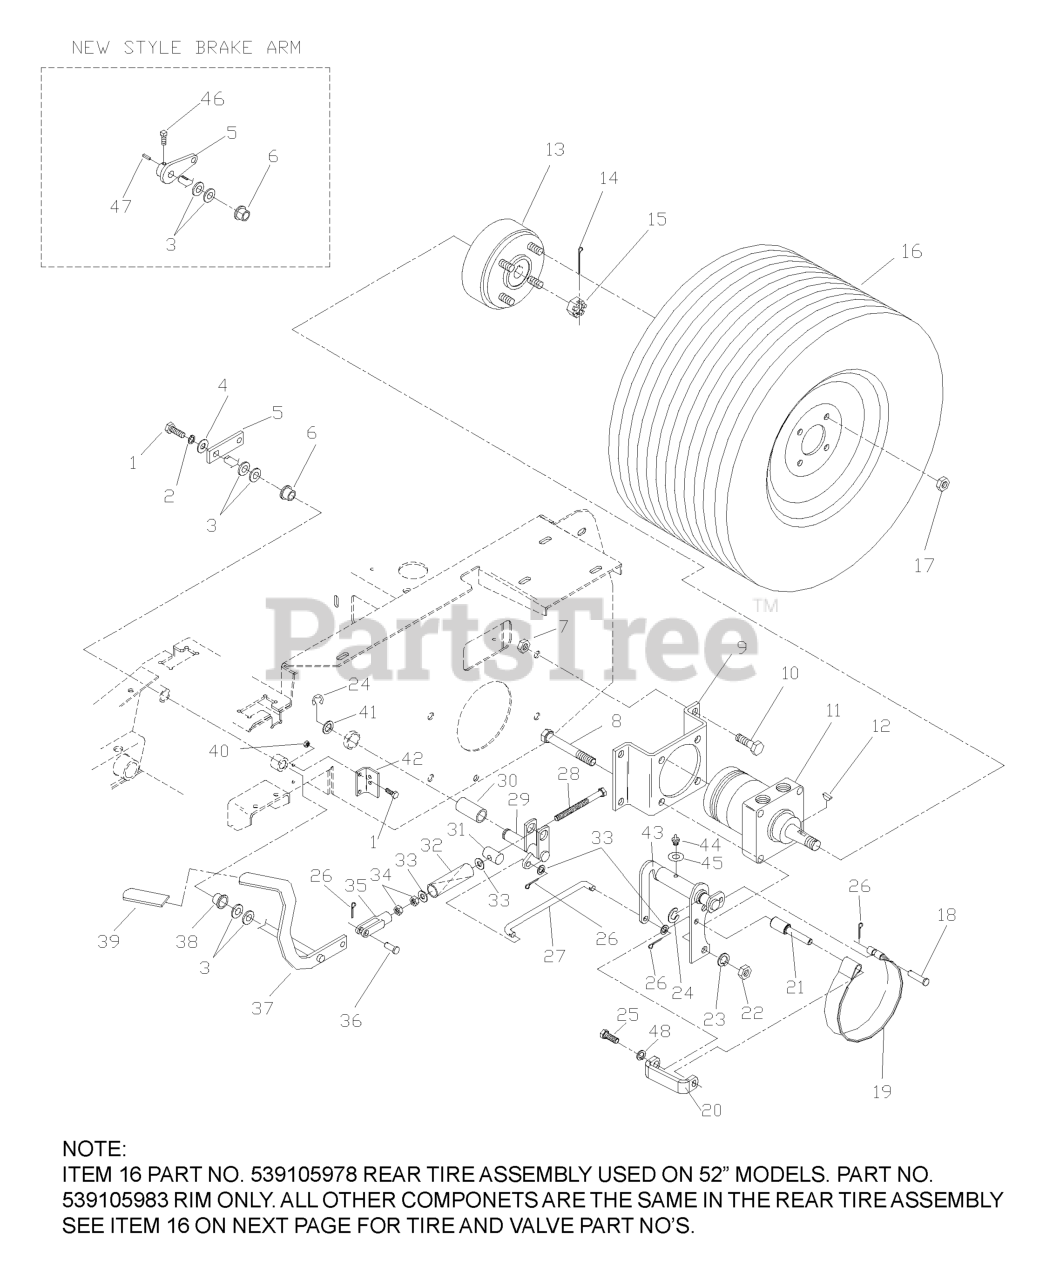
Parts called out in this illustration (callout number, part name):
1	HCS 1/4C X 3/4 HCS
2	LOCKWASHER 1/4"
3	WASHER, 7/16 DISC SPRING
4	WASHER 1/4 FLAT
5	ARM, PARK BRAKE
5	BRAKE ARM WELDMENT
7	NUT 1/2-13 HEX NYLOC ZD
8	HCS 1/2C X 2 3/4
9	MOTOR STANDOFF - PAINTED
10	HCS 1/2C X 1 1/4 SERRATED HEAD
11	MB WHEEL MOTOR
12	WOODRUFF KEY
13	HUB W/BRAKE DRUM
14	COTTER PIN
15	CASTLE-NUT
16	WHEEL/TIRE.ASM.24X12-12.SILVER
16	REAR TIRE/WHEEL ASM
16	TIRE.24X12-12.TURF.MASTER
16	12"RIM 2.5" NEG OFFSET 8.5" W
16	RIM 0 OFFSET 8.5" WIDE
16	VALVE STEM TR-412
17	LUG NUT 1/2F
18	CLEVIS PIN, 3/8 X 1 1/2
19	BRAKE BAND
20	BRAKE SUPPORT BRACKET
20	HCS 3/8 X 3 GD.8
21	BRAKE BAND PIVOT
22	NUT HEX 1/2
23	WASHER 1/2" SPLIT LOCK
24	E RING 3/4
25	HEX BOLT 3/8 X 1"
25	NUT 3/8C CENTERBLOCK
26	RP_COTTER PIN 1/8 X 3/4
27	BRAKE LINKAGE, LT.
27	BRAKE LINKAGE, RT.
28	HCS 3/8F X SPECIAL
30	BRONZE BEARING
31	TRUNION PIN
33	WASHER 3/8 SAE FLAT
35	YOKE-3/8-24 PLTD
36	CLEVIS PIN 3/8 X 1 1/8
37	BRAKE LEVER WIDMT
37	BRAKE ARM
39	GRIP, PARK BRAKE
40	NUT 1/4C CENTERLOCK
42	BRACKET
43	LT.BRAKE WLDMT
43	RT.BRAKE WLDMT
44	ZERK
46	SCREW 5/16C X 5/8 SQ HEAD
48	SLW 3/8 STD
